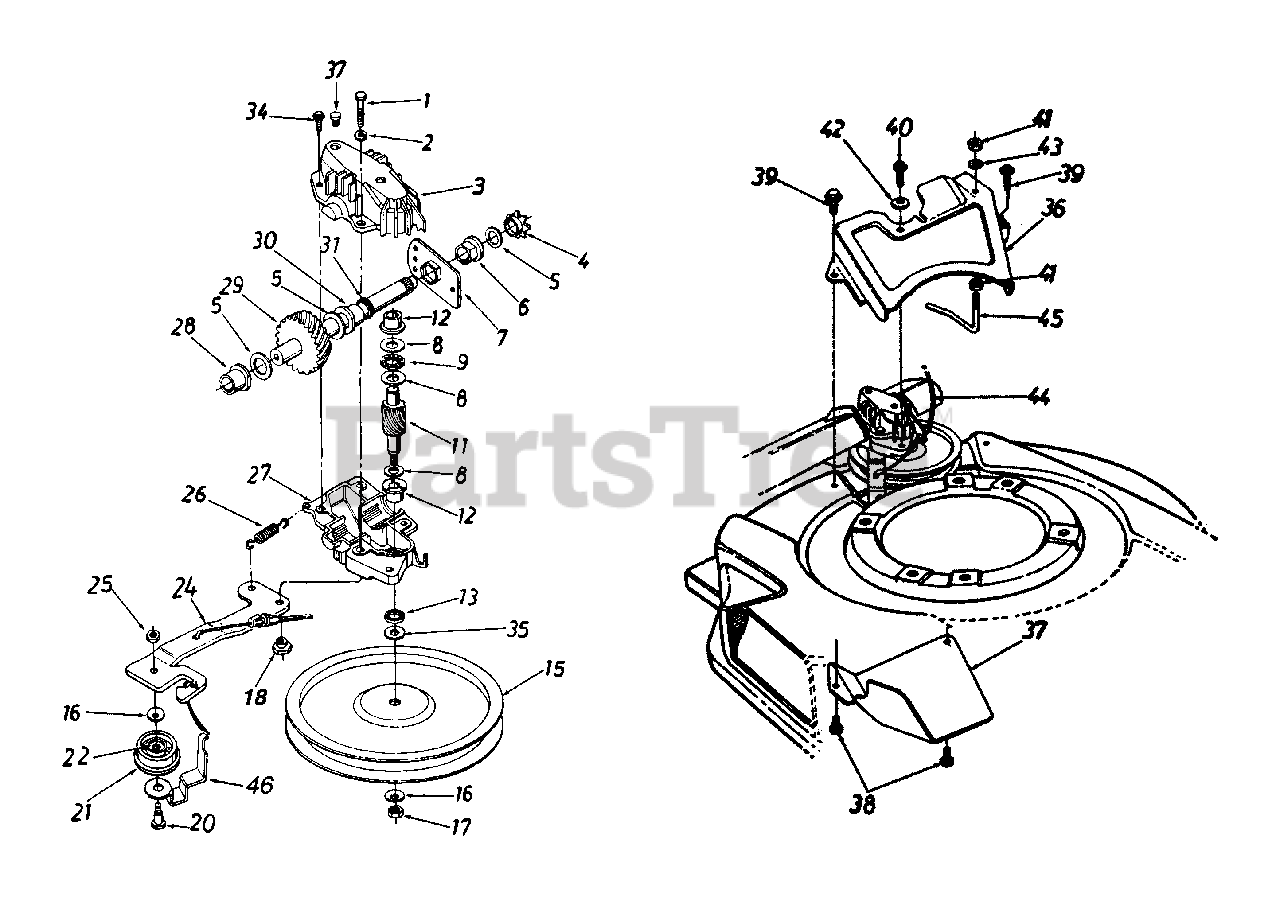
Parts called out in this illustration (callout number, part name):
1	Hex Bolt 1/4-20 x 1.25" Lg.
2	L-Wash. 1/4" I.D.
3	Upper Hsg. Half
4	#48 Sprocket 7 Tooth x 1/2 Pitch
5	Fl-Wash. 5/8" I.D. x .030
6	Hex Flange Brg. .631" I.D.
8	Thrust Wash. .382" I.D x .70" O.D.
9	Thrust Bearing .375" I.D. x .812" O.D.
11	11 Tooth Helical Gear
12	Flange Bearing
13	Oil Seal
15	Fl-Pulley 5.06" I.D.
16	Bell-Wash. .265" I.D. x .75"
17	Hex Nut 1/4-28 L.H. Thd.
18	Shld. Spacer .375" Dia. x .170
20	Shld. Bolt .375" Dia. x .40"
21	Fl-Idler Plastic 1.50" Dia.
22	Needle Brg. .375" x .375"
24	Idler Brk't. Ass'y.
25	Hex Patch L-Nut 1/4-28 Thd.
26	Extension Spring 1.12" Lg.
27	Lower Hsg. Half
28	Flange Bearing .56 Dia.
29	Shaft Ass'y.
30	Flange Bearing .629 Dia.
31	Oil Seal .625 Dia.
34	Hex B-Tap Scr. #10 x .62"
35	Hex Washer .26" x .88"
38	Hex B-Tap Scr. 1/4 x .38" Lg.
39	Hex AB-Tap Scr. 1/4 x .50" Lg.
40	Hex B-Tap Scr. 1/4 x .62" Lg.
41	Hex Nut 1/4-20 Thd.
42	Bell-Wash. .265" I.D. x .75"
43	L-Wash. 1/4" I.D.
44	S.R Cable-48" Lg.
45	S.R Belt Guard
46	Belt Guard
